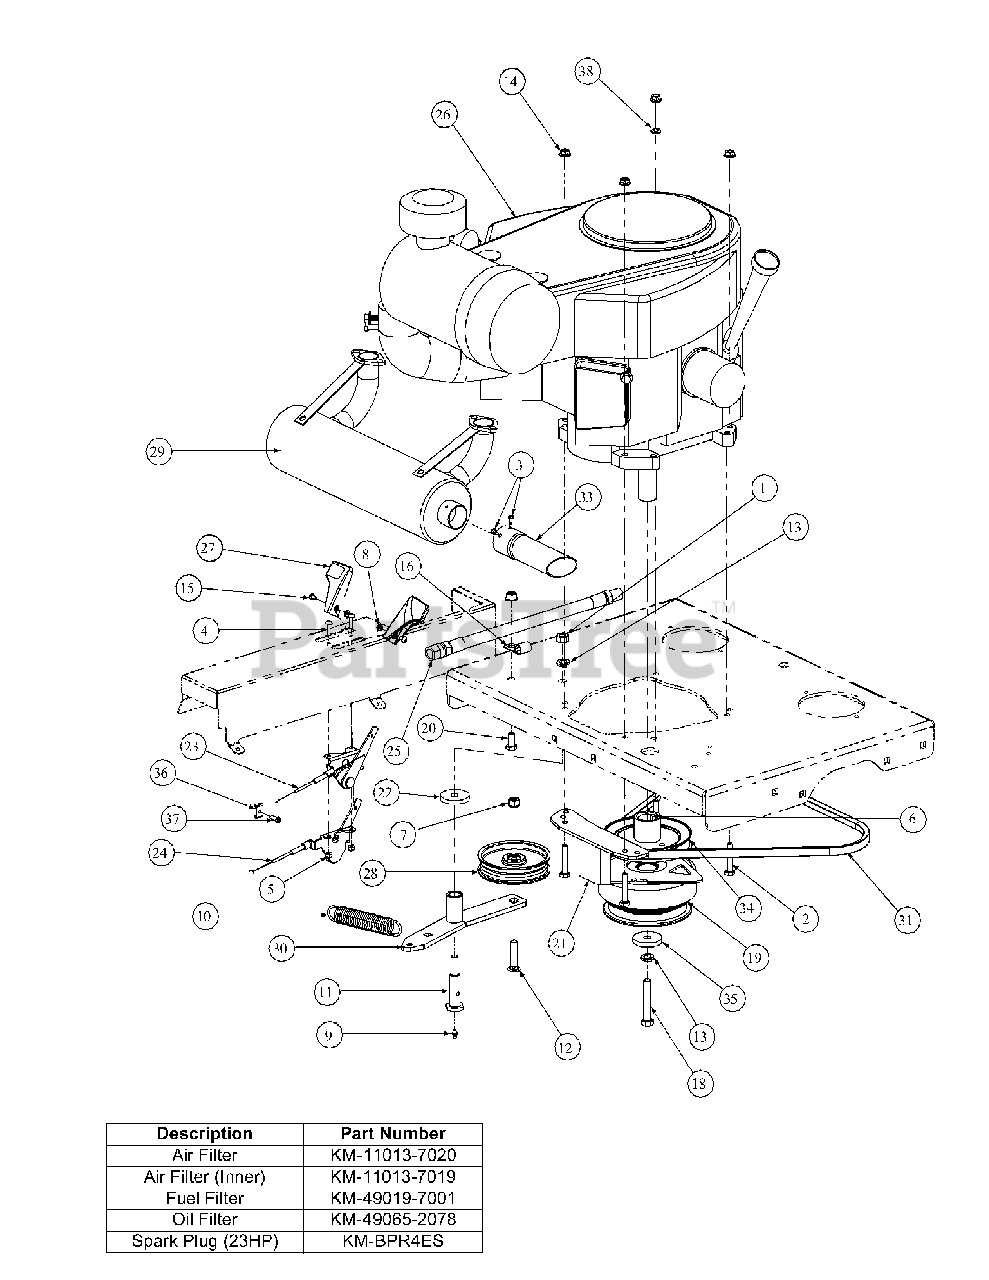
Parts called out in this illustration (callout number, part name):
1	Hex Nut, 7/16-14
2	HHCS, 5/16-18, 1-3/4
3	Screw, #8-32 x 0.375
4	Round Hd. Machine Screw, 10-32 x 3/4
5	Lock Nut, Nylon Insert, 10-32
6	Key, 1/4 x 1/4 x 3
7	Flange Lock, Hex Nut, 3/8-16
8	Nut Washer, W/Star, 8-32
9	Grease Fitting, 1/4-28 x 3/16
10	Extension Spring, 1.0 OD x 5.125
11	Shoulder Screw, 7/16-14
12	Hex Carriage Screw, 3/8-16, 1.75
13	Lock Washer, 7/16
14	Hexflange Lock Nut, 5/16-18
15	Machine Screw, 8-32, .375
16	Clip, Heat Shield Cable
18	Capscrew, 7/16-20 x 2.50
19	Clutch Brake, 1.125 ID
20	Hex Cap Screw, 3/8-16, .750
21	Retainer Clutch Assembly, Ogura
22	Flat Washer, 7/16 ID x 1.75 OD x .25
23	Choke, Control Cable, 43.0
24	Throttle, Control Cable, 39.0
25	Oil Drain Hose
26	23HP Kawasaki Engine
27	Control Throttle Knob
28	Flat Pulley with Flanges
29	Muffler Accessory, Kawasaki
30	Engine Idler Arm Assembly includes:
30	Bearing
30	Engine Idler Arm Assembly Cast
31	V Belt, A Section x .47.3
33	Muffler Accessory Exhaust Tube
34	Pump Drive Pulley
35	Flat Washer, 7/16 ID x 1.75 OD x .25
36	Bolt, M5 x 18
37	Choke Cable Clamp
38	Flat Washer, .320 ID x .591 OD x .078
KM-BPR4ES	Spark Plug (23HP)
